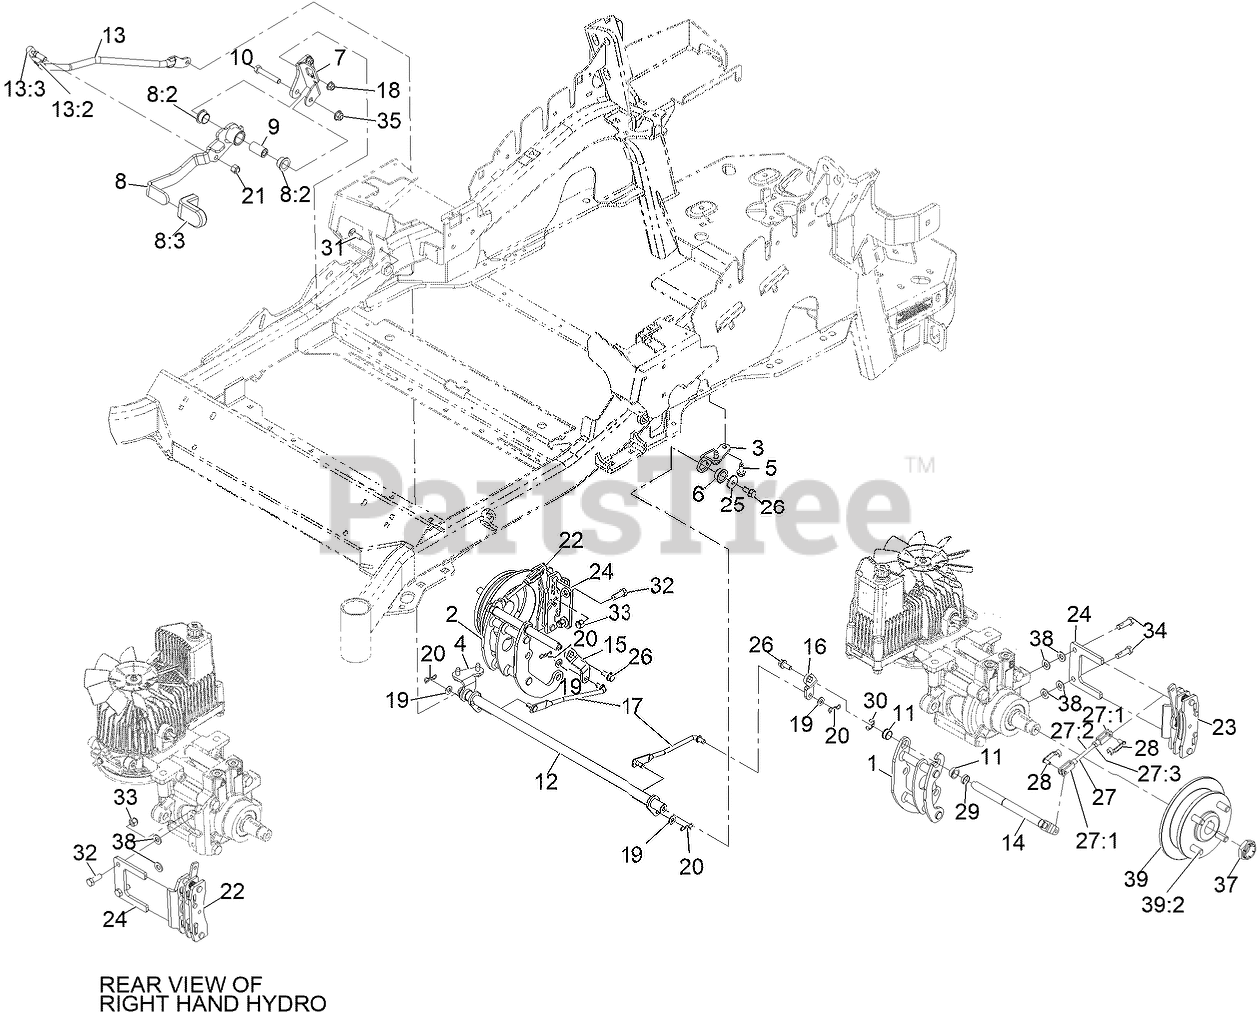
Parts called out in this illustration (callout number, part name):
1	MOUNT-BELLCRANK, LH
2	MOUNT-BELLCRANK, RH
3	MOUNT-PIVOT, LH
4	MOUNT-PIVOT, RH
5	Screw-HWH 5/16-18 X 3/4 Tf
6	BUSHING-FLANGE
7	BRACKET-MOUNT
8	Brake Lever ASM
8:2	BUSHING-FLANGE
8:3	GRIP-LEVER
9	HANDLE-PIVOT, BRAKE
10	SCREW-HH
11	BUSHING
12	Shaft-Cross
13	ASM, Front Linkage
13:2	END-TIE ROD, RH
13:3	NUT-HJ
14	BELLCRANK
15	ARM-INNER, RH
16	ARM-INNER, LH
17	MID-LINK, LONG
18	NUT-HF, NI
19	WASHER-PLAIN
20	PIN-COTTER, LOCKING
21	NUT-LOCK
22	Caliper-Brake, RH
23	Caliper-Brake, LH
24	PLATE-MOUNT, BRAKE
25	WASHER-FLAT
26	SCREW-HHF
27	REAR LINKAGE ASM
27:3	NUT-JAM
28	PIN-CLEVIS, SPRING
31	BOLT-CARR
32	SCREW-HH,
33	NUT-LOCK
34	Screw-HH, Patch
35	NUT-HF, NI
37	LOCKNUT
38	WASHER-FLAT
39	Wheel Hub ASM
39:2	STUD-WHEEL
